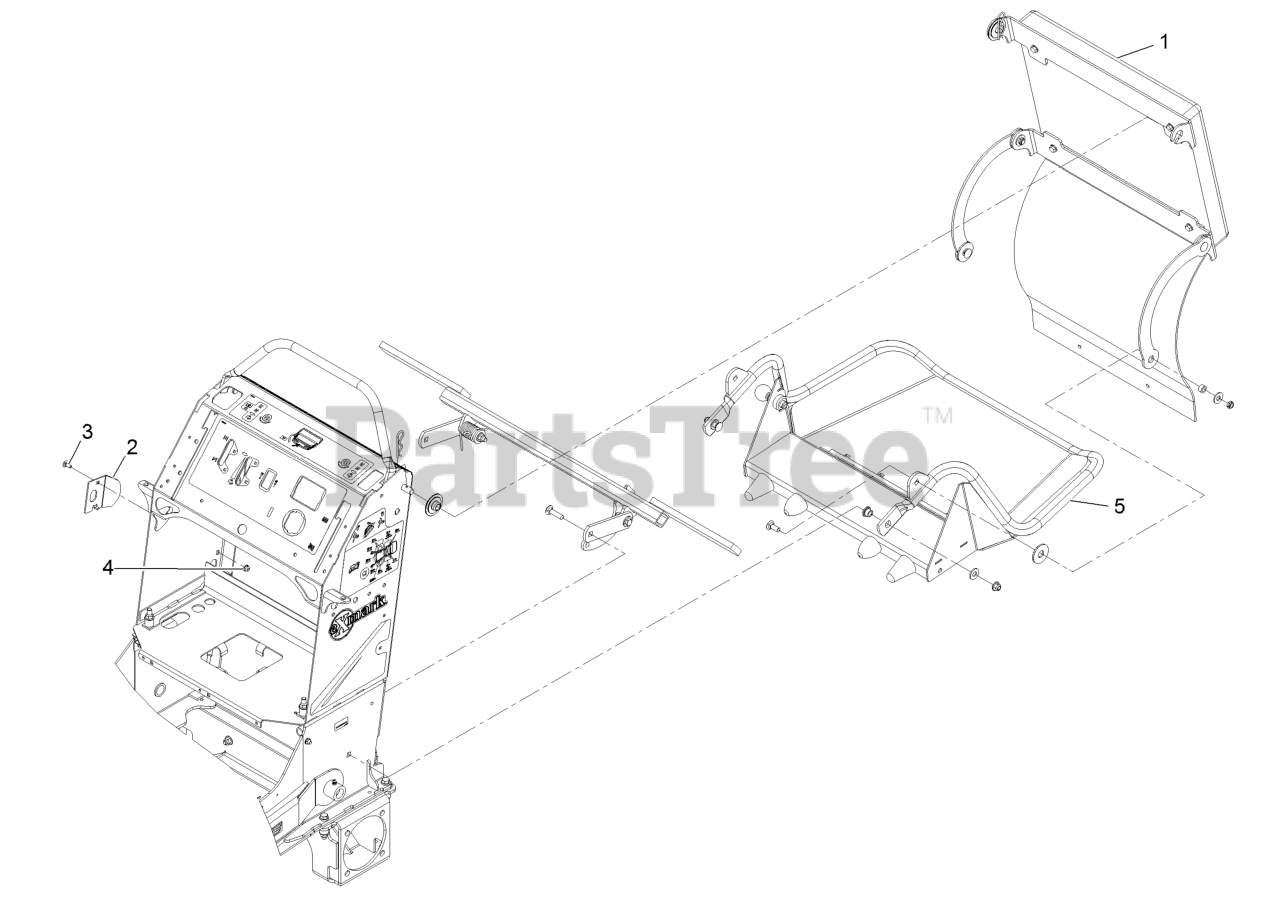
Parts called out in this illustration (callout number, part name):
1	ASM, Cushion
2	Plate-Striker
3	Bolt-Carriage 1/4-20 X 5/8
4	Nut-Nyloc 1/4-20 Flg
5	ASM,Platform
